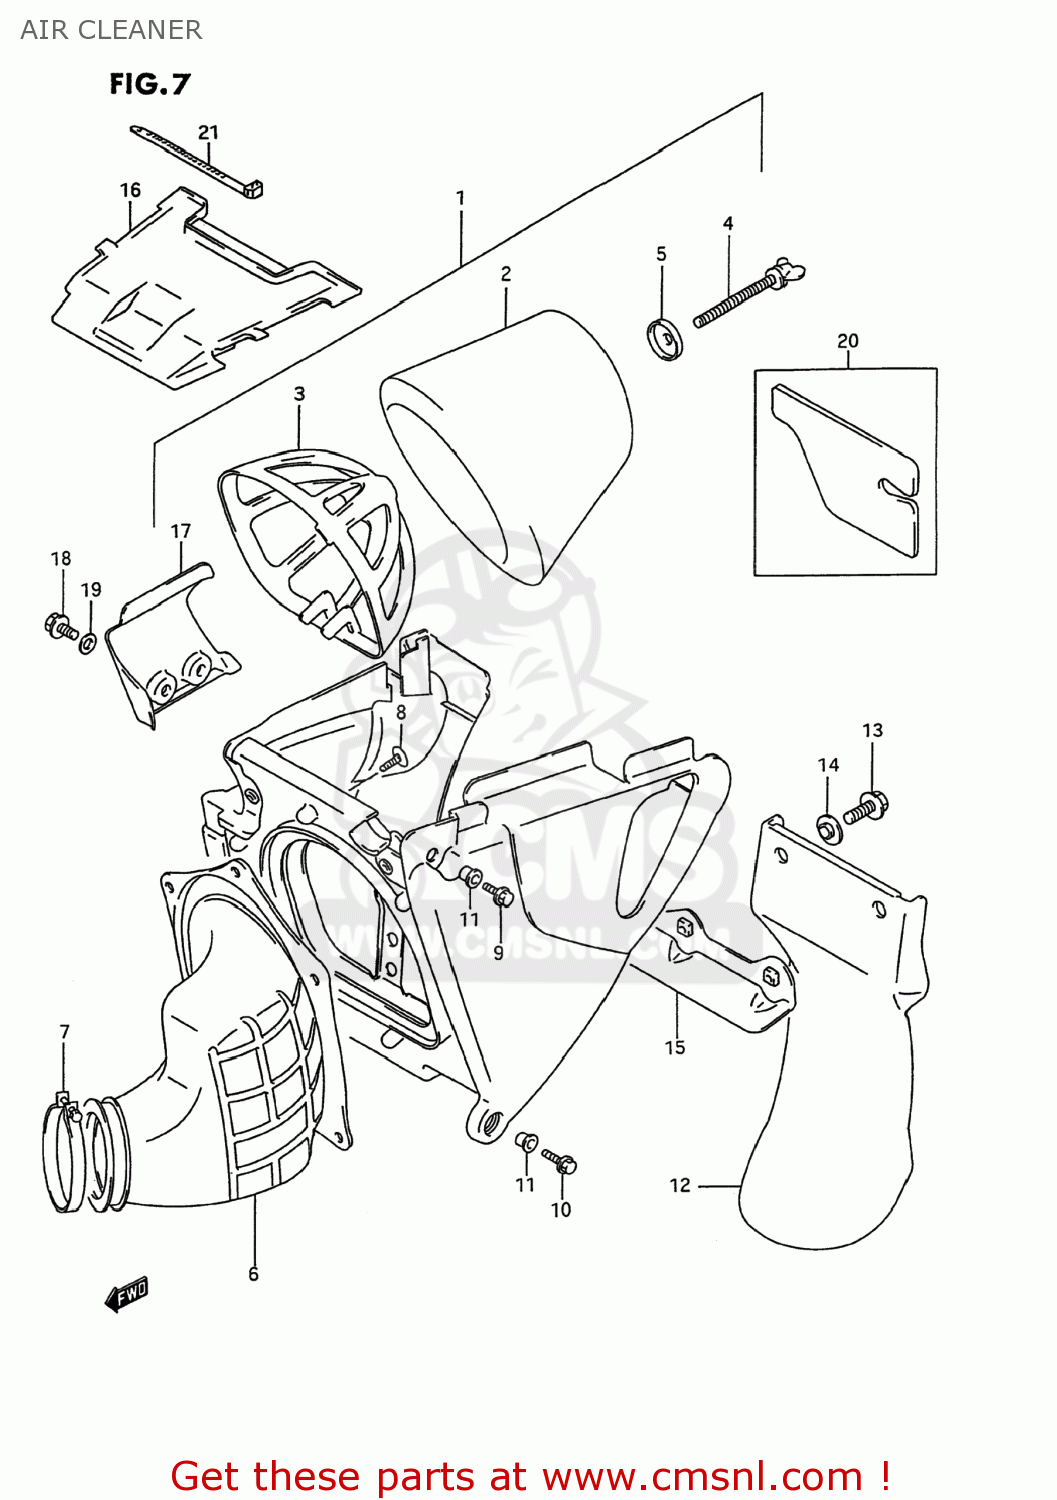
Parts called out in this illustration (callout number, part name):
1	CLEANER ASSEMBLY
2	FILTER ASSY
3	HOLDER,FILTER
4	BOLT,WING
5	WASHER,AIR CLEANER
6	TUBE,OUTLET
7	CLAMP
8	SCREW
9	BOLT
10	SCREW
11	WASHER
12	GUARD,MUD
13	BOLT
14	WASHER
15	PLATE,MUDGUARD
16	CAP,AIR CLEANER
17	COVER,AIR CLEANER,R NO.2
18	BOLT
19	WASHER
20	GUARD,MUD,UPPER
21	CLAMP(L:129)
